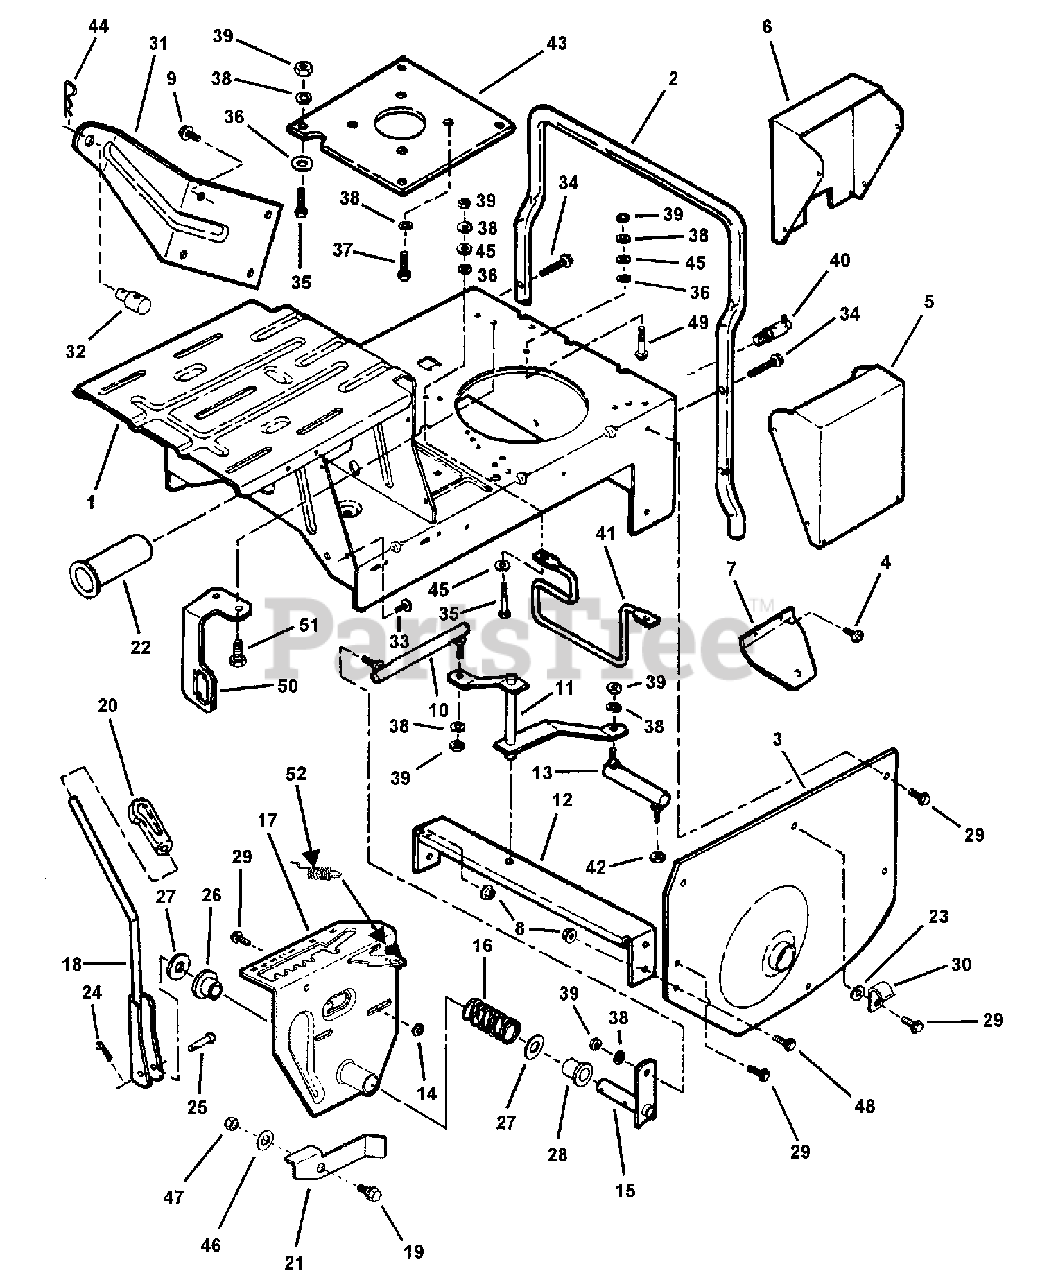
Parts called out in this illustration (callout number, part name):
1	CASE, Commercial Main (Weldment)
2	BUMPER, Rear
3	FENDER, Left Hand
4	SCREW, 1 /4-20 x 1/2" Hex Washer Self-Tap
5	COVER, Battery
6	COVER, Switch
7	PLATE, Choke
8	NUT, 5/16-18 Hex Flange Lock
9	SCREW, 5/16-18 x 3/4" Hex Washer Self-Tap
10	LINK, Shift (Long)
11	ARM, Shift (Weldment)
12	BRACE, Cross
13	LINK, Shift (Short)
14	NUT, 5/16-18 Hex
15	ARM, Shift Handle (Weldment)
16	SPRING, Shift Handle
17	ASSEMBLY, Shift Detent
18	HANDLE, Shift (Weldment)
19	BOLT, 5/16-18 Shoulder
20	KNOB, Shift Handle
21	LEVER, Over-Ride
22	BUSHING, Pilot
23	WASHER, 5/16" Internal Tooth Lock
24	COTTER-PIN, 3/32 x 3/4"
25	PIN, 1/4 x 1-3/4" Tapered Clevis
26	BUSHING, Nylon
27	WASHER, Thrust
28	BUSHING, Nylon
29	SCREW, 5/16-18 x 5/8" Hex Washer Self-Tap
30	CLIP, Wire
31	WING, Rear Deck
32	SWIVEL
33	FASTENER, Ratchet
34	SCREW, 5/16-18 x 1-1/2" Self-Tapping
35	SCREW, 5/16-24 x 1" Hex Head Cap
36	RETAINER, 5/16 Bolt
37	SCREW, 3/8-16 x 1" Self-Tapping
38	WASHER, 5/16" Split Lock
39	NUT, 5/16-24 Hex, Grade 5
40	ASSEMBLY, Oil Drain
41	GUIDE, Belt (9.48" Bolt Pattern Bent Top, 6.0" Belt Gap)
42	NUT, 5/16-24 Hex Flange Lock
43	PLATE, Engine
44	HAIRPIN, 3/32 x 1-1/2"
45	WASHER 11/32 x 11/16 x 1/16"
46	WASHER, 7/16" Flat
47	NUT, 5/16-18 Nyloc
48	SCREW, 5/16-18 x 3/4" Hex Cap
49	SCREW, 5/16-24 x 1-3/4" Hex Head Cap, Grade 5
50	BRACKET, Switch
51	SCREW, #10-32 x 1/4" Hex Washer Head, Self-Tap
52	SPRING
